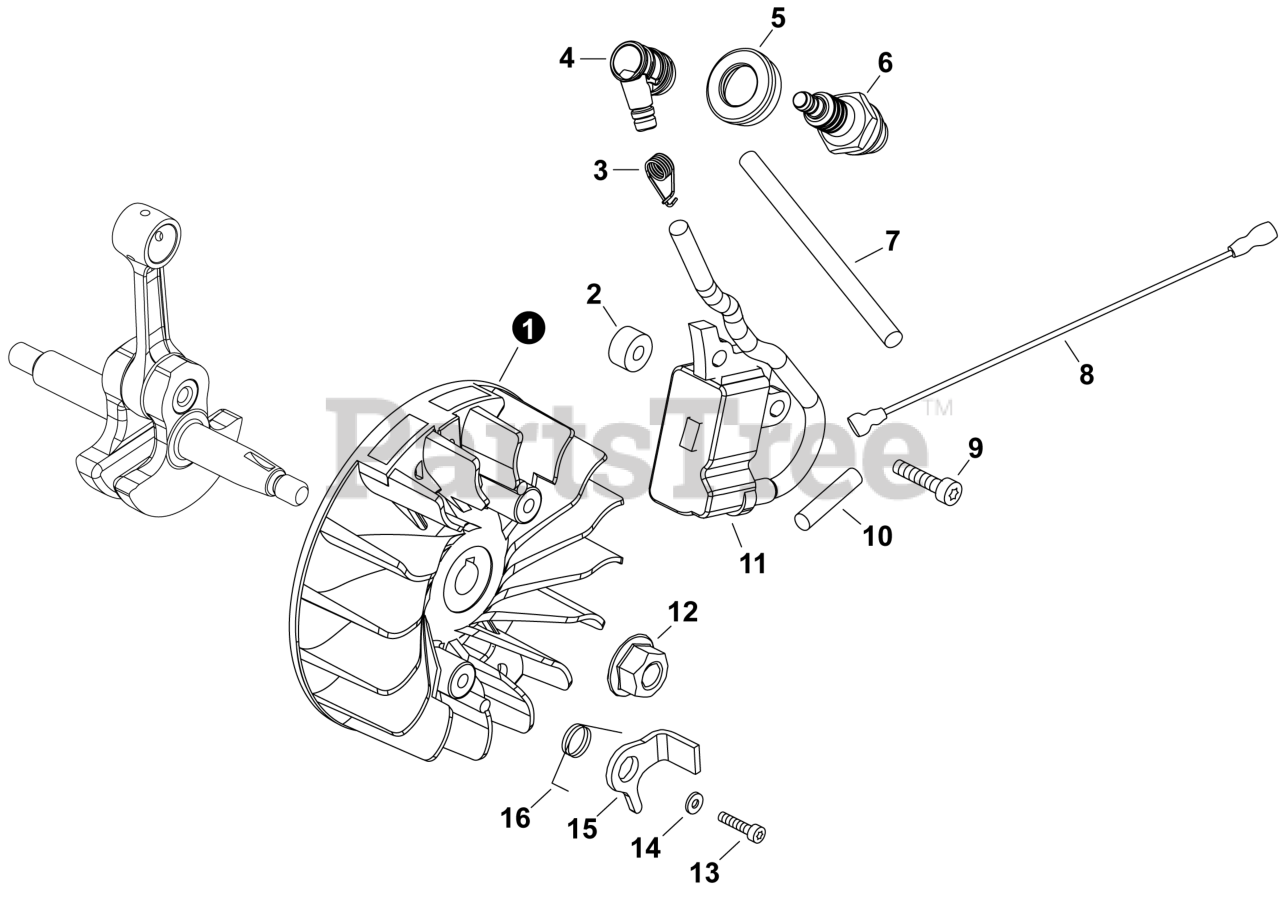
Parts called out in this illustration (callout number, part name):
1	FLYWHEEL
2	COLLAR 5
3	TERMINAL, SPARK PLUG
4	CAP, SPARK PLUG
5	SEAL, SPARK PLUG
6	SPARK PLUG - BPMR8Y
7	TUBE, INSULATOR
8	LEAD - IGNITION
9	BOLT, TORX 5×16
10	TUBE, INSULATOR
11	COIL, IGNITION
12	NUT, FLANGE M8×1.25
13	BOLT, TORX 5×12
14	SPACER 5.2×8×2.1
16	SPRING, TORSION
